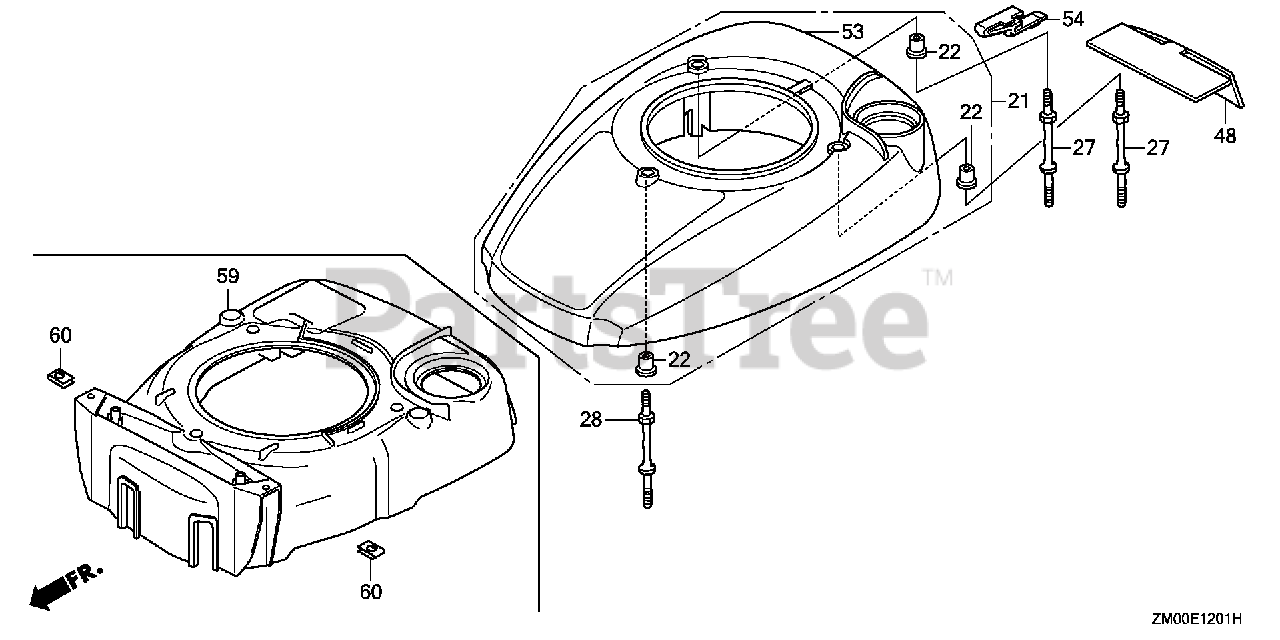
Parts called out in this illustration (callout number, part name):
21	COVER, FAN *NH1* (BLACK)
22	COLLAR, FAN COVER
27	BOLT, STUD (H=42.5MM)
28	BOLT, STUD (H=42.5MM)
28	BOLT, STUD (H=39.5MM)
48	RUBBER, FAN COVER
